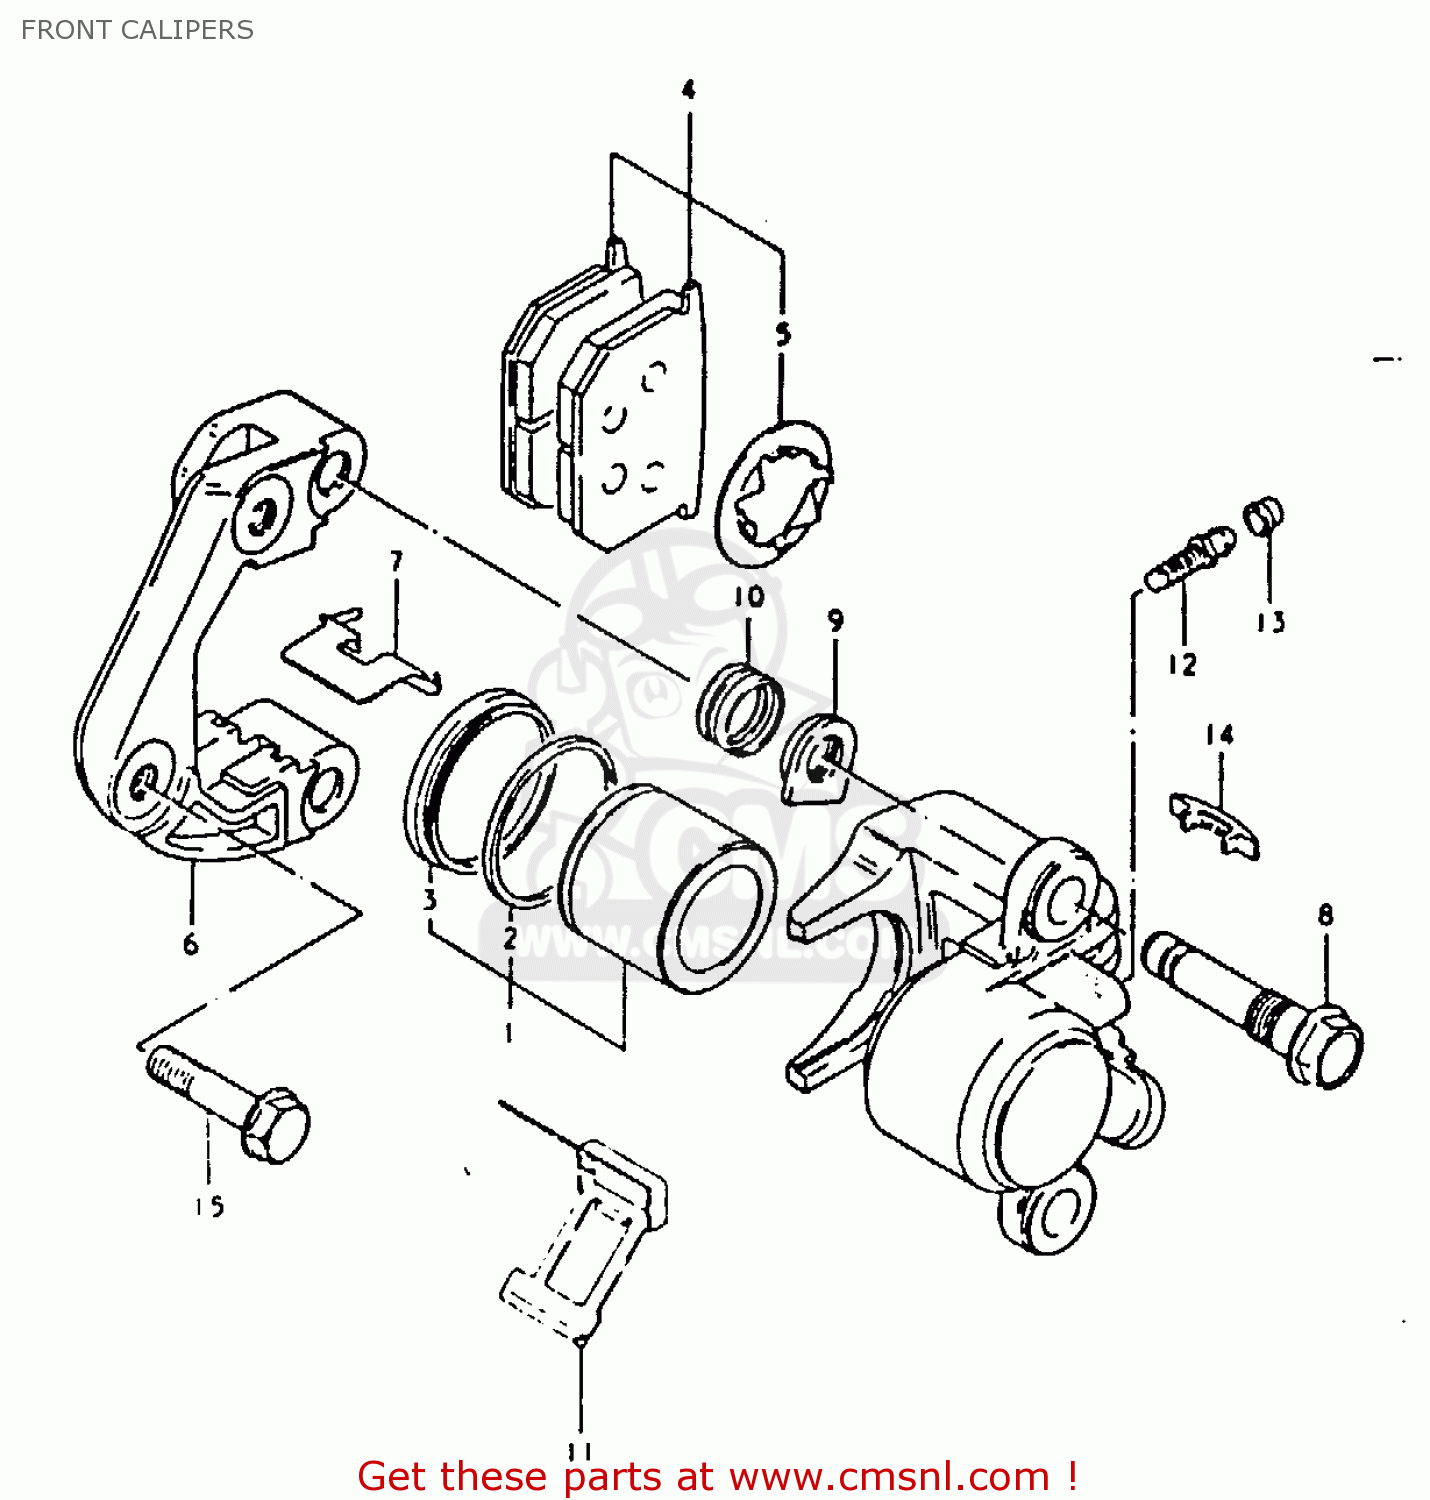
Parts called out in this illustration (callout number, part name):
1	PISTON SET
2	SEAL,PISTON
3	BOOT,PISTON
4	PAD & SHIM SET (MCA)
5	SHIM,PAD
6	HOLDER,CALIPER,LEFT
7	GUIDE,PAD
8	AXLE,CALIPER
9	NUT,CALIPER AXLE
10	BOOT
11	SPRING
12	BREATHER
13	CAP,BLEEDER PL
14	COVER,INDICATOR
15	BOLT
